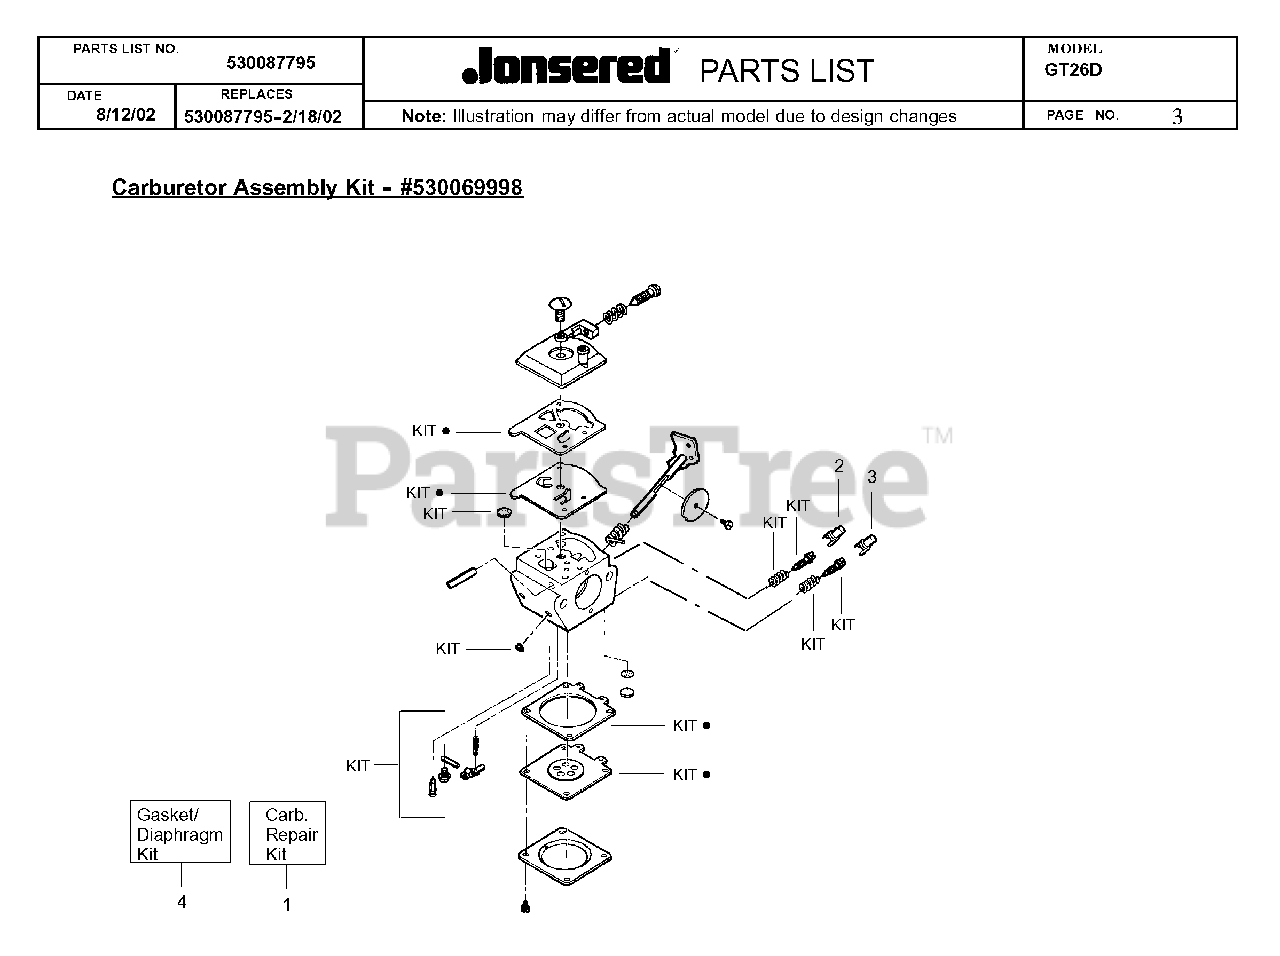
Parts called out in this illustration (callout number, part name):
1	CARB REPAIR KIT
2	LIMITER CAP-HIGH
3	LIMITER CAP-LOW
4	GASKET/DIAPHRAGM KIT
